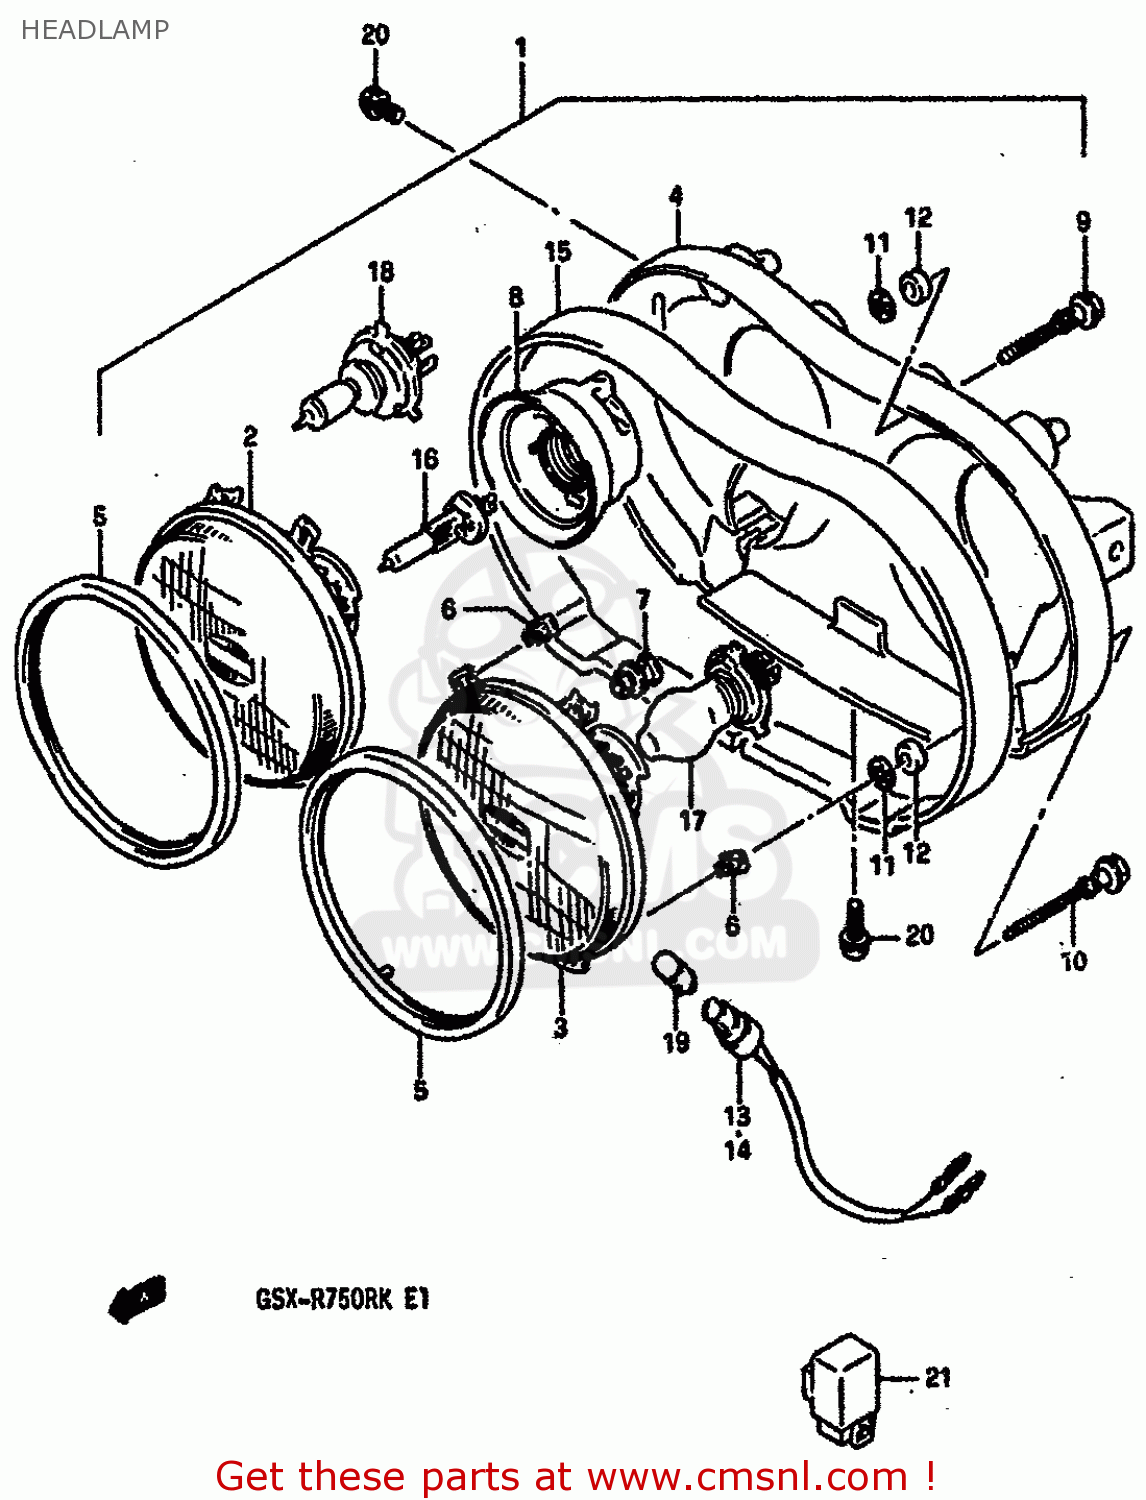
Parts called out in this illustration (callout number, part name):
1	HEADLAMP ASSY
2	UNIT,HEADLAMP RH
3	LAMP UNIT
4	HOUSING
5	RING,RETAINING
6	NUT,HEADLAMP ADJUSTER
7	SCREW,SPHERICAL
8	COVER,SOCKET
9	SCREW,HEADLAMP ADJUST
10	SCREW,ADJUSTER
11	WASHER
12	BUSHING
13	SOCKET
14	SOCKET & CORD
15	GASKET,HEADLAMP
16	BULB(12V55W/H1/P14.5S/OSRA,PHI
17	BULB (12V, 60/55W, H4)
18	BULB(12V60/55W,H4)
19	BULB(12V4W)
20	SCREW
21	RELAY ASSY,HEADLAMP
